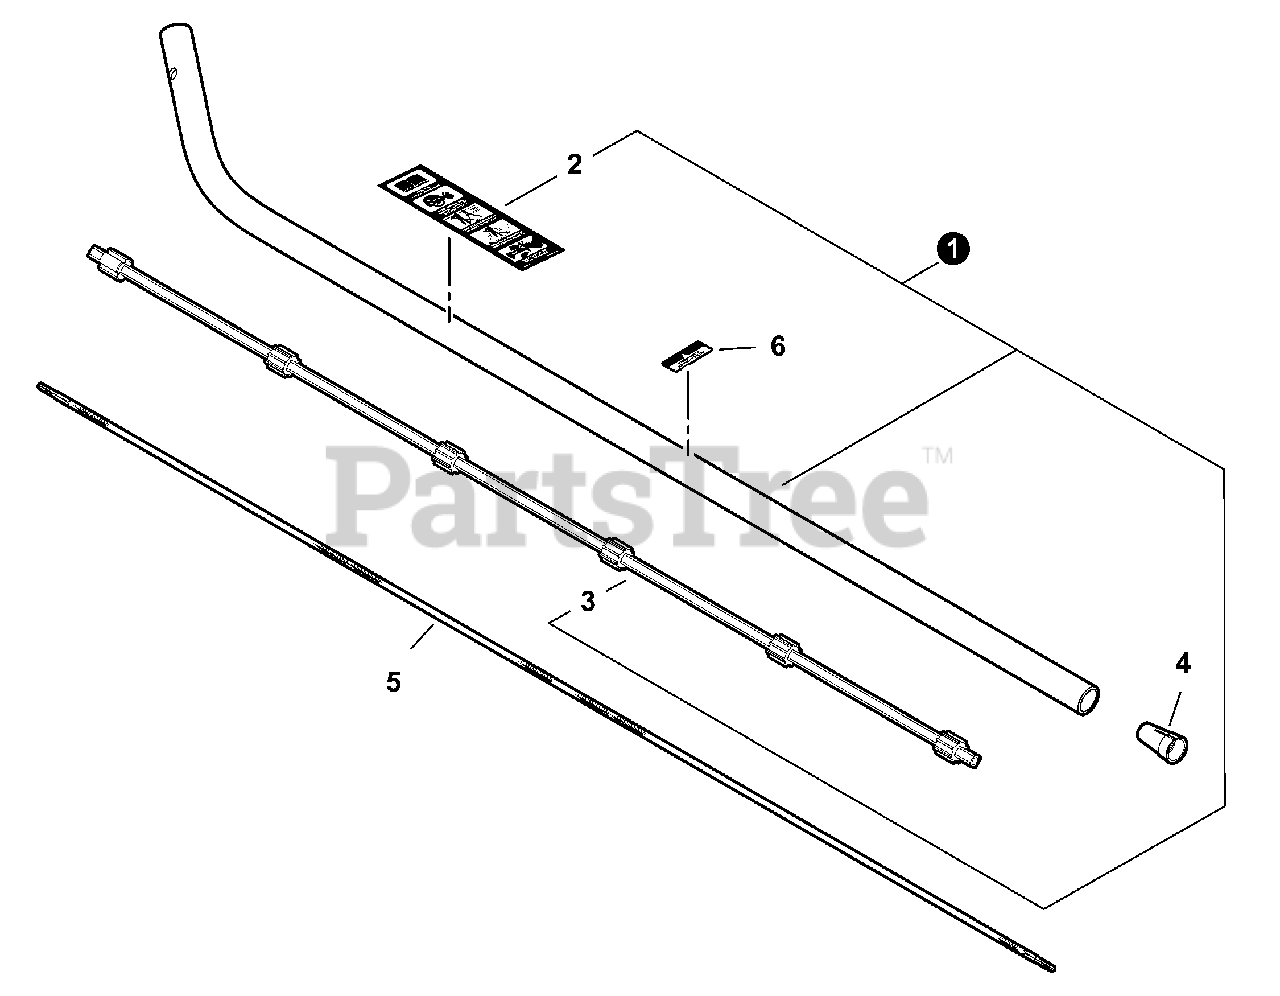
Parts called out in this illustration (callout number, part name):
1	MAIN PIPE ASSY
2	LABEL, CAUTION
4	GUIDE, SHAFT
5	DRIVESHAFT - FLEXIBLE
6	LABEL, HANDLE
